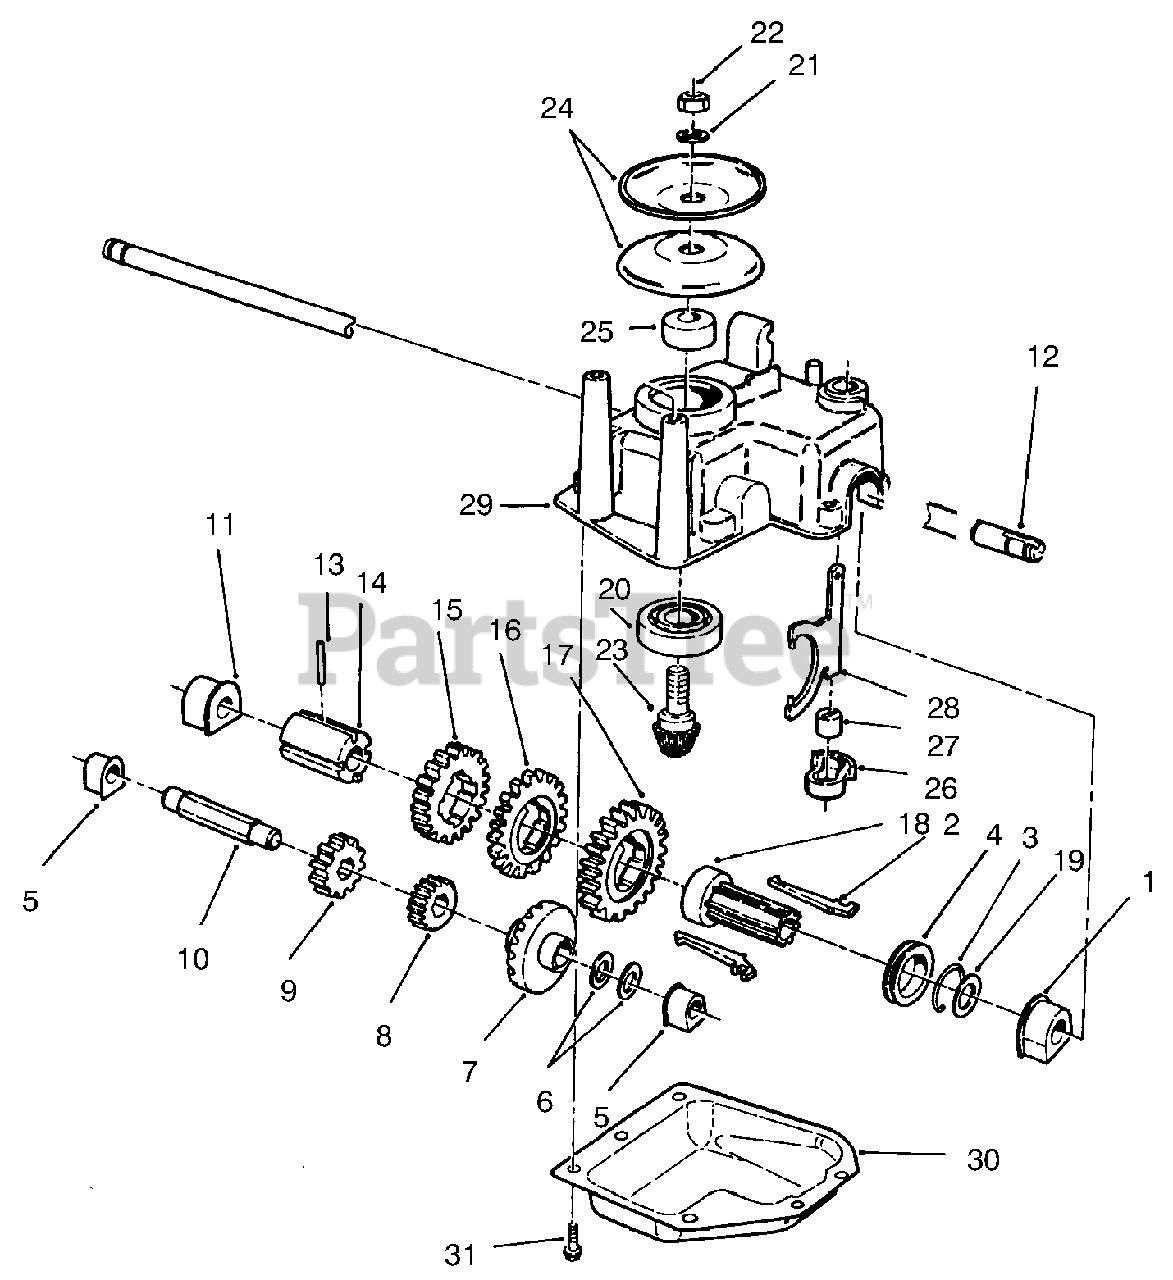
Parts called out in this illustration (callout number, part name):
1	Bushing-Output Shaft
2	Key-Shift
3	Clip-Spring
4	Collar-Shift
6	Washer-Thrust
7	15 T Pinion
8	Pinion 20t 2nd Gear
9	Pinion 25t 3rd Gear
10	Shaft-Intermediate
11	Bushing-Output
12	Shaft-Output
13	Pin-Spirol
14	Sleeve-Gear
15	Gear 39t 3rd Gear
16	Gear 44t 2nd Gear
17	Gear 49t 1st Gear
18	Sleeve-Shift Key
19	Washer-Thrust
20	Bearing-Ball
21	Washer-Flat
22	Nut-Lock
23	Pinion-Bevel
24	Pulley-Half
25	Spacer-Pulley
26	Retainer-Shift-Fork
27	Bushing-Yoke
28	Yoke-Shift
29	Gearcase-Upper 3 Sp
30	Cover-Gearcase
31	Screw-HH
